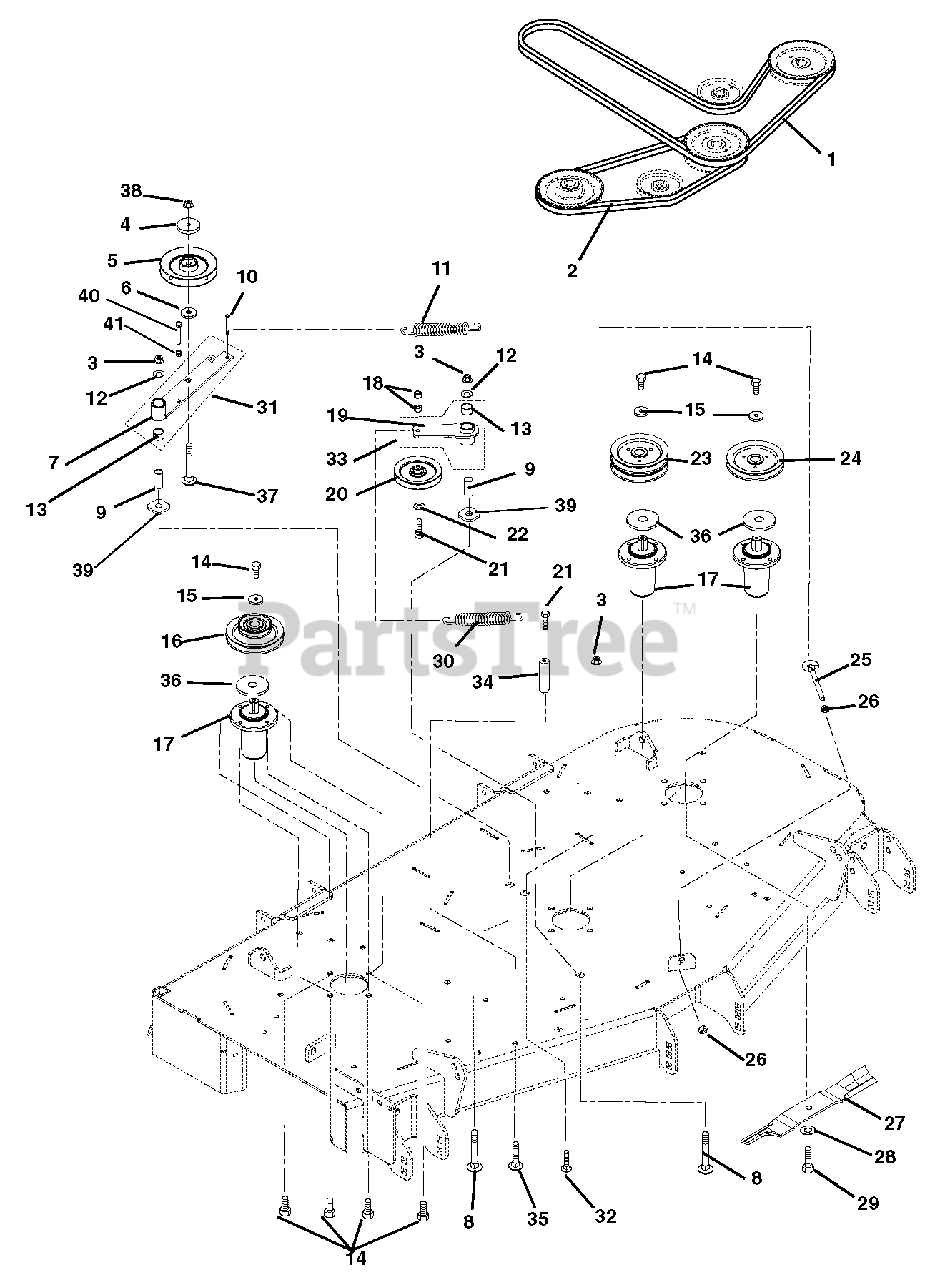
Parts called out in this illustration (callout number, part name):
1	Belt, 184.4" Long, PTO Drive Hex (195)
2	V-Belt, 63" Long Cog B-Section (195)
3	Nut, .50-13 Nyloc Flange
4	Cap, Idler Bearing Sealing
5	Sheave, .50"ID x 6.00"OD V-Idler
6	Bushing, Spacer .502 x .997 x .50
7	Weldment, Idler Arm
8	Bolt, Round Head Square Neck .50-13 x 3.50 Grade 5
9	Bushing, Spacer .505/.500 x .999/.996 x 2.05/2.03
10	Bolt, Shoulder EP .38-16 x .30 Hex
11	Spring, Extension (Deck Idler)
12	Washer, Flat Steel .563 x 1.38 x .109
13	Bushing, 1.00 x 1.125 x 1.936
14	Bolt, Hex .38-16 x 1.00
15	Washer, Flat Steel .406 x 1.50 x .245
16	Sheave, Double, 1" ID x 6.75" x 4.25" OD (195)
17	Spindle Assembly (196)
18	Nut, Locking Center .38-16
19	Weldment, Idler Arm
20	Assembly, V-Idler 5.00 O.D.
21	Bolt, Hex .38-16 x 2.25
22	Washer, Flat Steel .406 x .812 x .065
23	Sheave, Double 1" ID x 6.75" OD (195)
24	Sheave, Single 1" ID x 6.75" OD (195)
25	Bolt, .38-16 x 4.50 .62 Diameter Eye
26	Nut, Hex, Jam .375-16
27	Blade, Mower (20.50") (195)
28	Washer, Bellville .63 x 1.625 x.14
29	Bolt, Hex .62-18 x 1.75 Grade 8
30	Spring, Extension
31	Assembly, PTO Idler Pivot Arm (Includes item # 7 and item # 13)
32	Bolt, Round Head Square Neck .50-13 x 1.5, Full Thread, Grade 5
33	Assembly, Idler Arm (Includes item # 13 and item # 20 )
34	Nut, Coupling .375-16 x 1.75
35	Bolt, Round Head Square Neck .38-16 x 1.00
36	Retainer, Grease
37	Bolt, Round Head Square Neck .50-13 x 3.00 Grade 5
38	Nut .50-13 Nyloc Flange
39	Washer, Flat .640 x 1.75 x .250
40	Bolt, Hex .38-16 x 2.75
41	Nut, Hex .38-16
